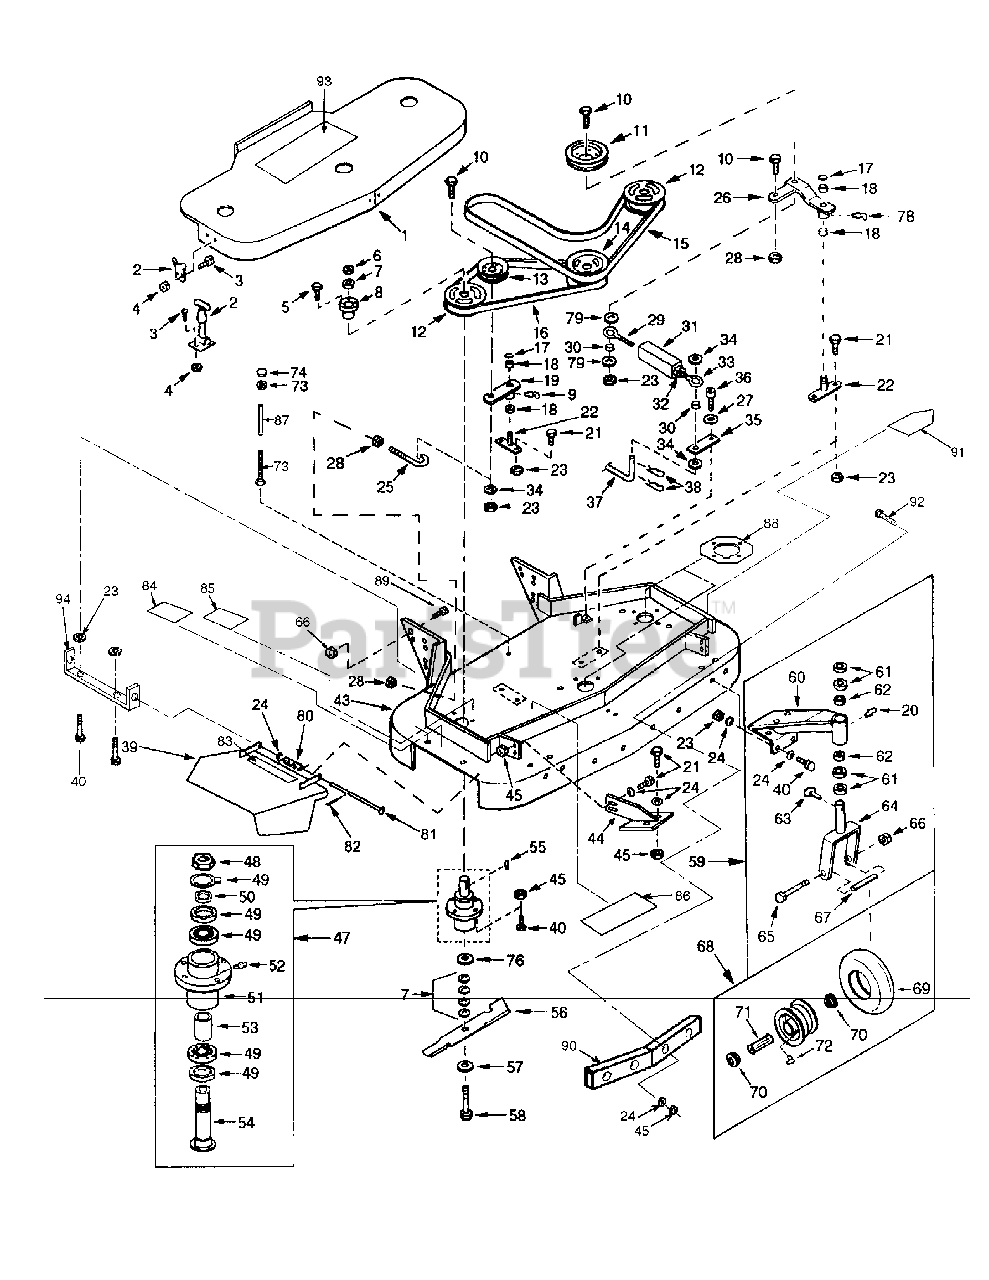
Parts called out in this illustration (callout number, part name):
1	Deck Cover
2	Rubber Latch
3	Machine Screw, 10-24 x 1/2 Round Hd.
4	Hex Nut, 10-24 Nylock
5	Cap Screw, 1/4-20 x 3/4 Hex Hd.
6	Hex Nut, 5/8-11
7	Blade Spacer
8	Pulley Bushing
9	Grease Fitting, 1/4-28, 90x
10	Cap Screw, 3/8-16 x 2-1/2 Hex Hd.
11	Idler, Deck Take-up
12	Deck Pulley
13	Deck Idler
14	Double Pulley
15	Drive Belt
16	Drive Belt
17	E-Ring, External
18	Sintered Bushing
19	Pivot Arm, Deck Idler Pulley
20	Grease Fitting, 1/4-28, Taper, Str.
21	Cap Screw, 3/8-16 x 1 Hex Hd.
22	Idler Pivot
23	Hex Nut, 3/8-16 Nylock
24	Flat Washer, 3/8, Small O.D.
25	Rod, Belt Tensioner
26	Pivot Arm, Deck Take-up Idler Pulley
27	Shim Washer, 3/4 x 1/2 x 1/16
28	Hex Nut, 3/8-16
29	Eyebolt, L.H.
30	Sleeve
31	Turnbuckle
32	Hex Nut, 5/16-18
33	Eyebolt, R.H.
34	Flat Washer, 3/8, Large O.D.
35	Clutch Link
36	Shoulder Bolt, 1/2 X 3/8
37	Rod, Blade Clutch
38	Hairpin, 3/8-7/16
39	Discharge Chute
40	Cap Screw, 3/8-16 x 1-1/4 Hex Hd.
41	Cap Screw, 1/2-13 x 1-1/4 Hex Hd.
42	Lock Washer, 1/2 Heavy
43	Cutter Deck
44	Caster Support
45	Hex Nut, 3/8-16 Stover
46	Belt Guide
47	Spindle Assembly
48	Hex Nut, 1-1/8-12 UNF, Jam
49	Kit, Spindle Repair
50	Seal Spacer
51	Spindle Housing
52	Grease Fitting
53	Internal Spacer
54	Spindle
55	Key, 1/4 x 1/4 x 2
56	Rotary Blade, 16-1/2
57	Flat Washer, 5/8
58	Cap Screw, 5/8-11 x 9-1/2 Hex Hd.
59	Caster Assembly
60	Caster Bracket
61	Caster Spacer
62	Bushing, Caster Bracket
63	Lynch Pin, 7/16 x 1-7/8
64	Caster Yoke
65	Cap Screw, 1/2-13 x 5-1/2 Hex Hd.
66	Hex Nut, 1/2-13 Nylock
67	Sleeve, Caster Wheel Bearing
68	Caster Wheel Assembly
69	Tire, Caster Wheel
70	Bearing Retainer, Caster Wheel
71	Roller Bearing, Caster Wheel
72	Grease Fitting, 1/4-28, 45x
74	Protective Cap
75	Channel, Rubber
76	Flat Washer, 1-1/2 x 5/8 x .055
77	Flat Washer, 3/8, Thick
78	Grease Fitting
79	Flat Washer, 5/16 USS
80	Torsion Spring
81	Deflector Pivot Pin Ass'y
82	Cotter Pin, 1/8 x 1
83	Decal, "Width Cut"
84	Decal, Rotating Blade
85	Decal, Warning Safety
86	Decal, Warning Shield
87	Spacer, Belt Guard
88	Plate, Spindle Backing
89	Bolt, Carriage
90	Bumper, 48"
91	Decal, Danger
92	Bolt, Carriage
93	Label, Command Deck
94	Bracket, Deflector
95	Bolt, Carriage
